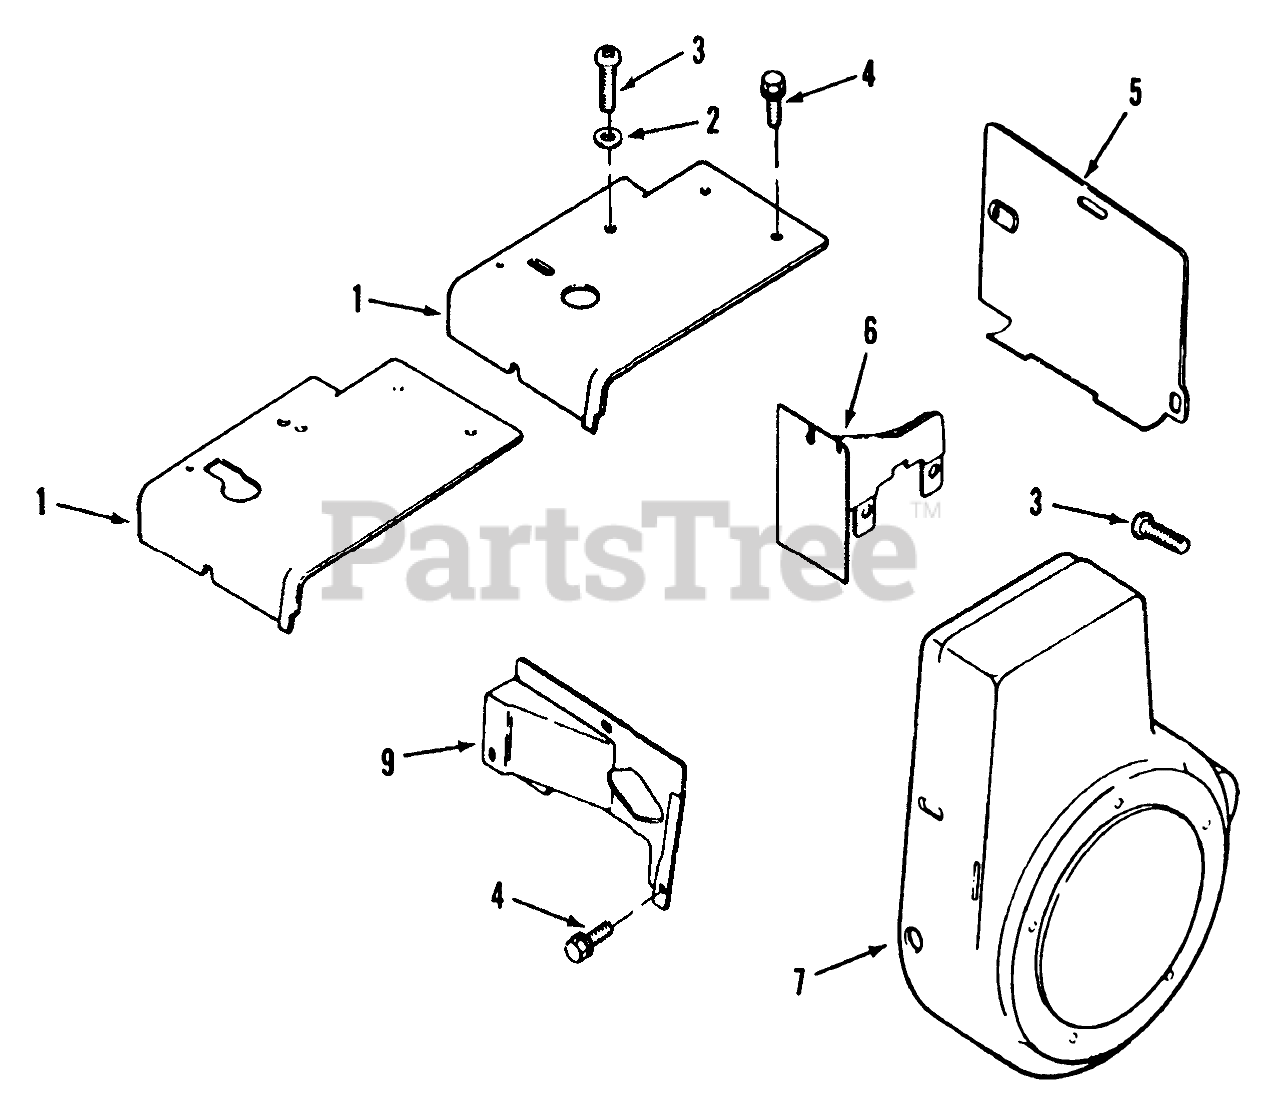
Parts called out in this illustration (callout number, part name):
1	Baffle-Head
2	Washer
3	Screw-Pozidriv T.H.
4	Screw Hex Hd
5	Baffle-Cylinder
6	Baffle-Inner
7	Blower Housing
9	Baffle-SideAir
